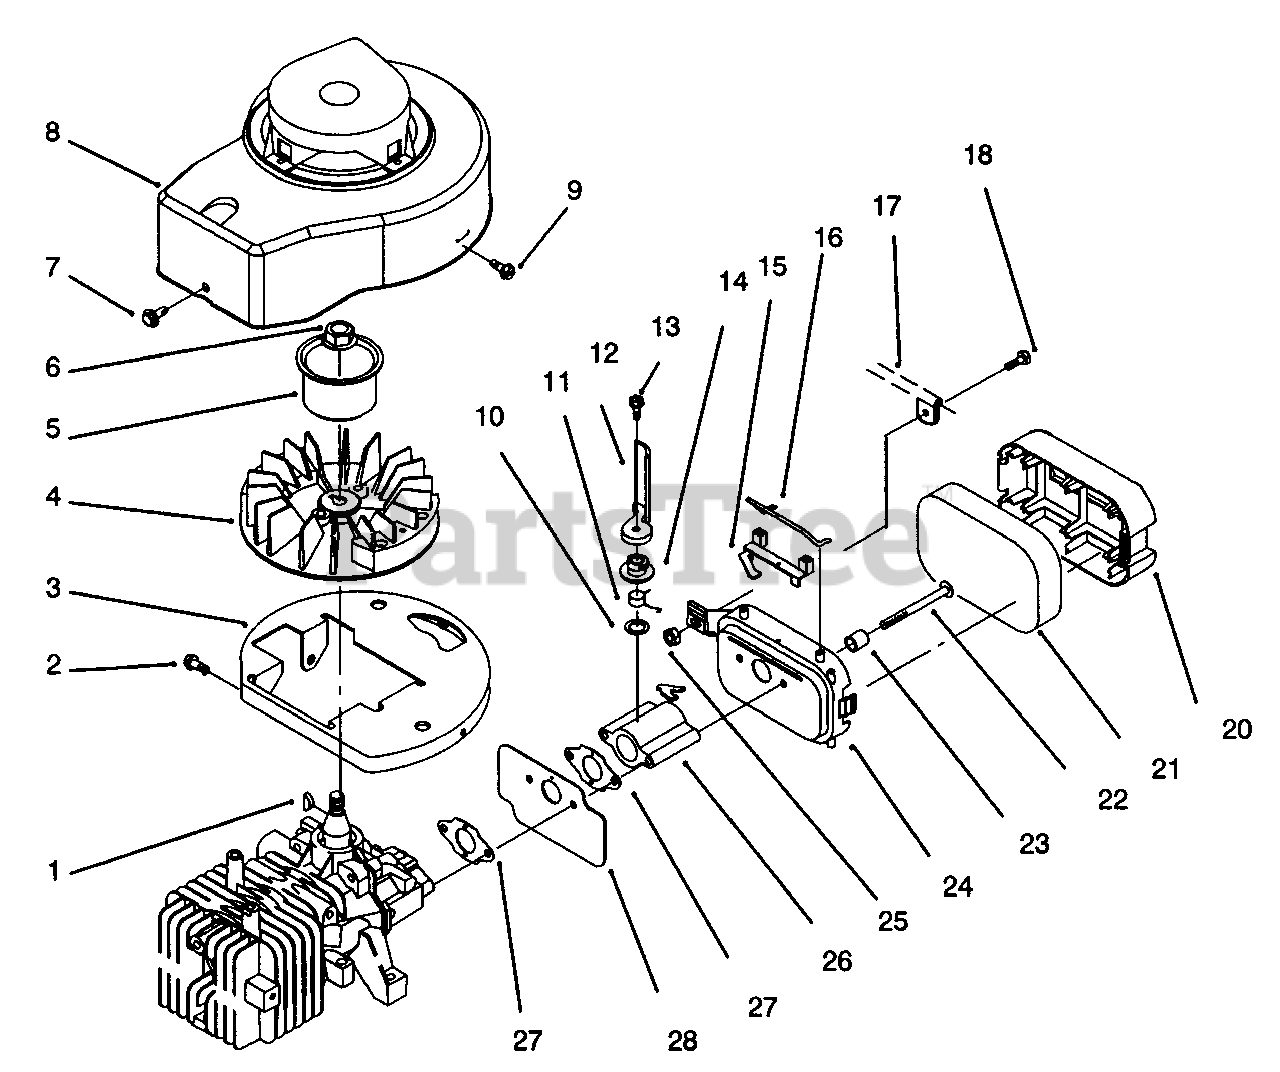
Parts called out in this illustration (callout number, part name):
1	Key-Crankshaft
2	Screw
3	Base-Shroud
4	Flywheel Assembly
5	Hub-Starter
6	Nut-Hex. Flange
7	Screw
8	Shroud Assembly
11	Spring-Throttle
12	Air Vane
14	Collar-Air Vane Adj.
16	Retainer
17	Cable Throttle Ref.
20	Cover-Air Filter
21	Element-Air Filter
22	Screw-Carburetor
24	Base-Air Filter
25	Nut
26	Carburetor Assembly
27	Gasket-Carburetor
28	Shield-Carburetor
